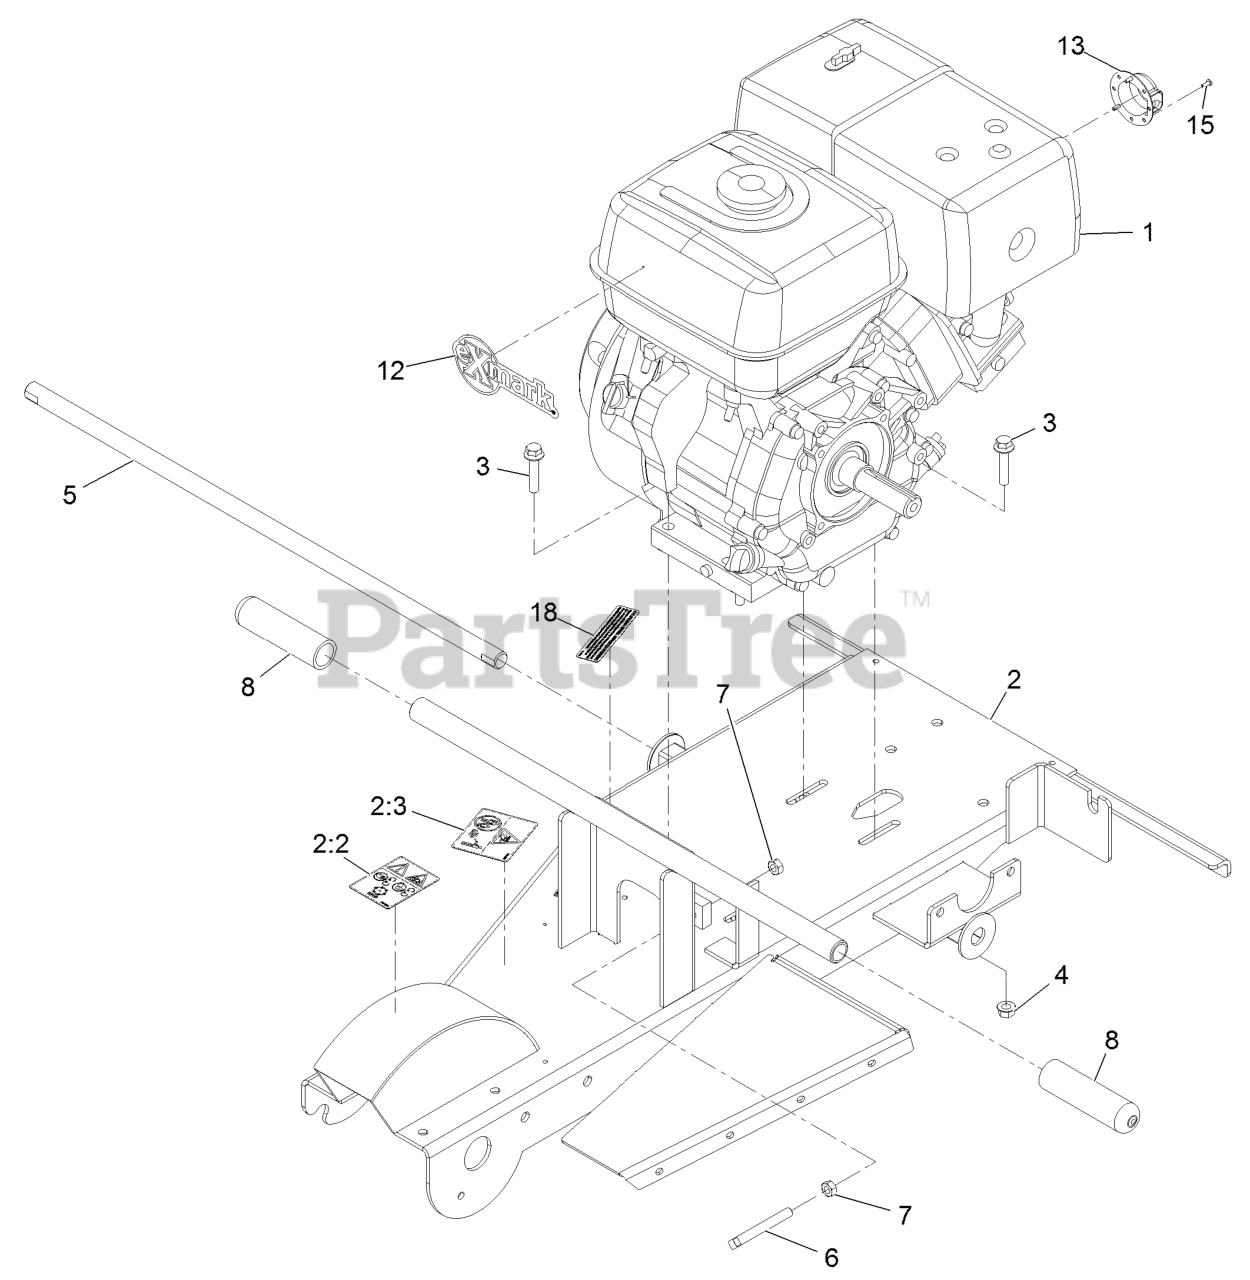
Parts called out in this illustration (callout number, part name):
2	Frame Asm,
2:2	DECAL-DANGER
2:3	DECAL-CAUTION
3	SCREW-HHF
5	BAR-AXLE
6	SCREW-SET, SQH
7	NUT-HEX
8	GRIP-HANDLE
13	DEFLECTOR-EXHAUST, HONDA
15	SCREW-TAP
18	DECAL-ARRESTER, SPARK
